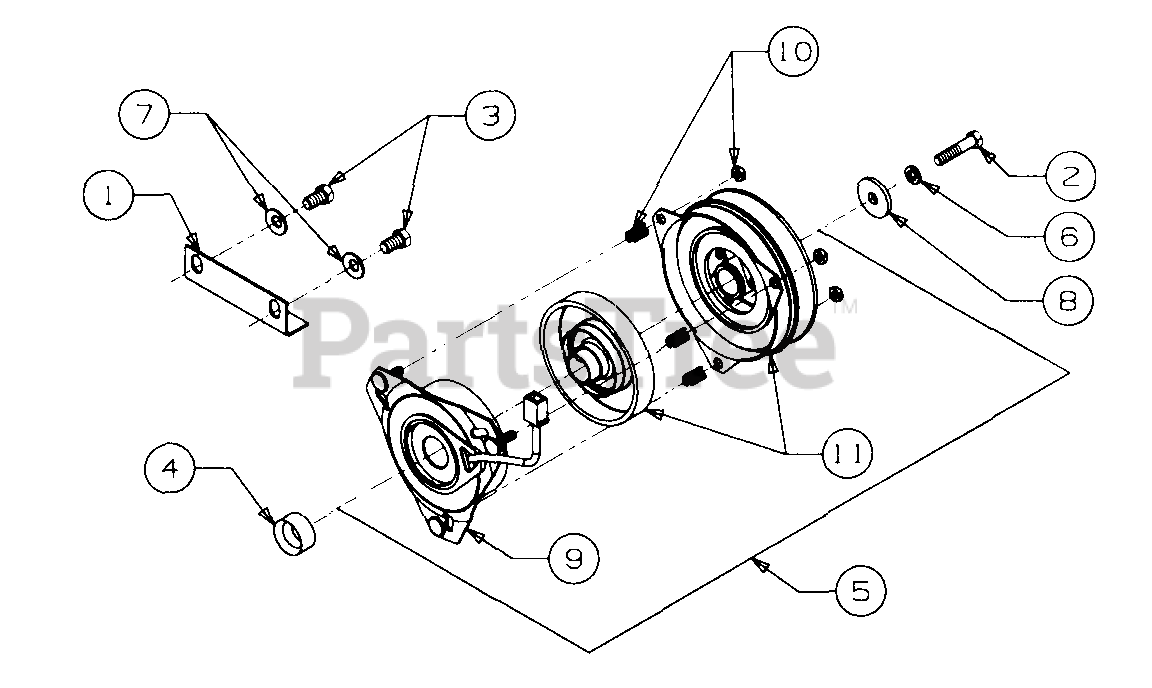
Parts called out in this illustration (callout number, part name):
3	Screw, Hex Cap, 7/16-14 x .75 Lg GR5
4	Spacer
5	Clutch Assy, PTO
6	Washer, Lock, 3/8
7	Washer, Bell, .45 x 1.0 x .062 Thk
8	Washer, Flat, .445 x 1.5 x .1 72 Thk Hdn
9	Field Assy
10	Mounting Accessories
11	Kit, Armature and Rotor
